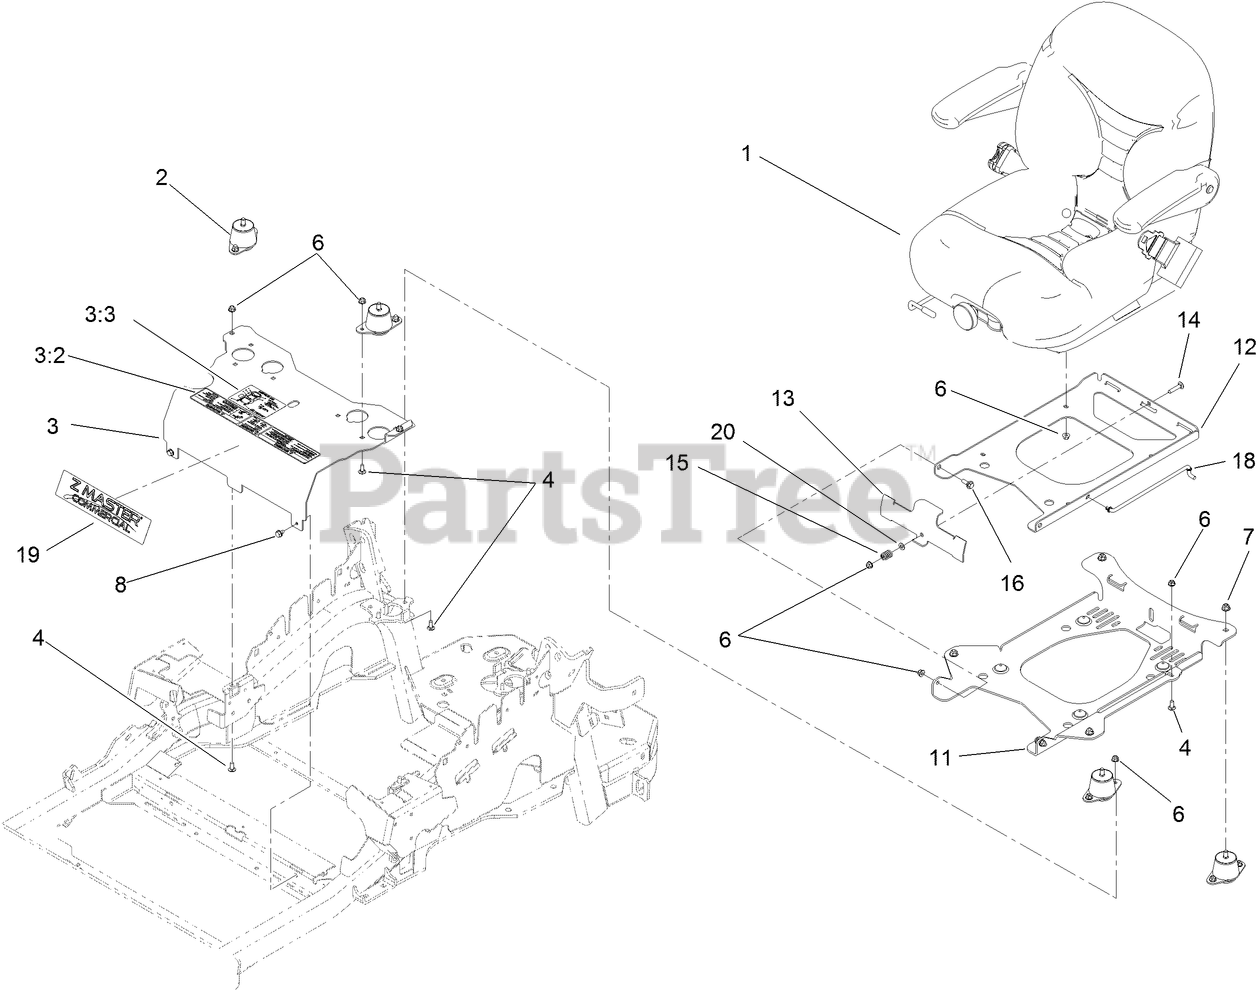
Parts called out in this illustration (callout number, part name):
1	SUSPENSION SEAT ASM
2	ISOLATOR-SEAT
3	MOUNT-SEAT
3:2	DECAL-CONSOLE
3:3	DECAL-SERVICE AID
4	SCREW-CARR
6	NUT-HF, NI
7	NUT-HF, NI
8	SCREW
11	PLATE-TILT, SEAT SUPPORT
12	PLATE-FRAME, SEAT
13	PLATE-LATCH, SEAT
14	BOLT-CARR
15	SPRING-COMPRESSION
16	SCREW-SHOULDER
18	ROD-PROP
20	WASHER-PLAIN
